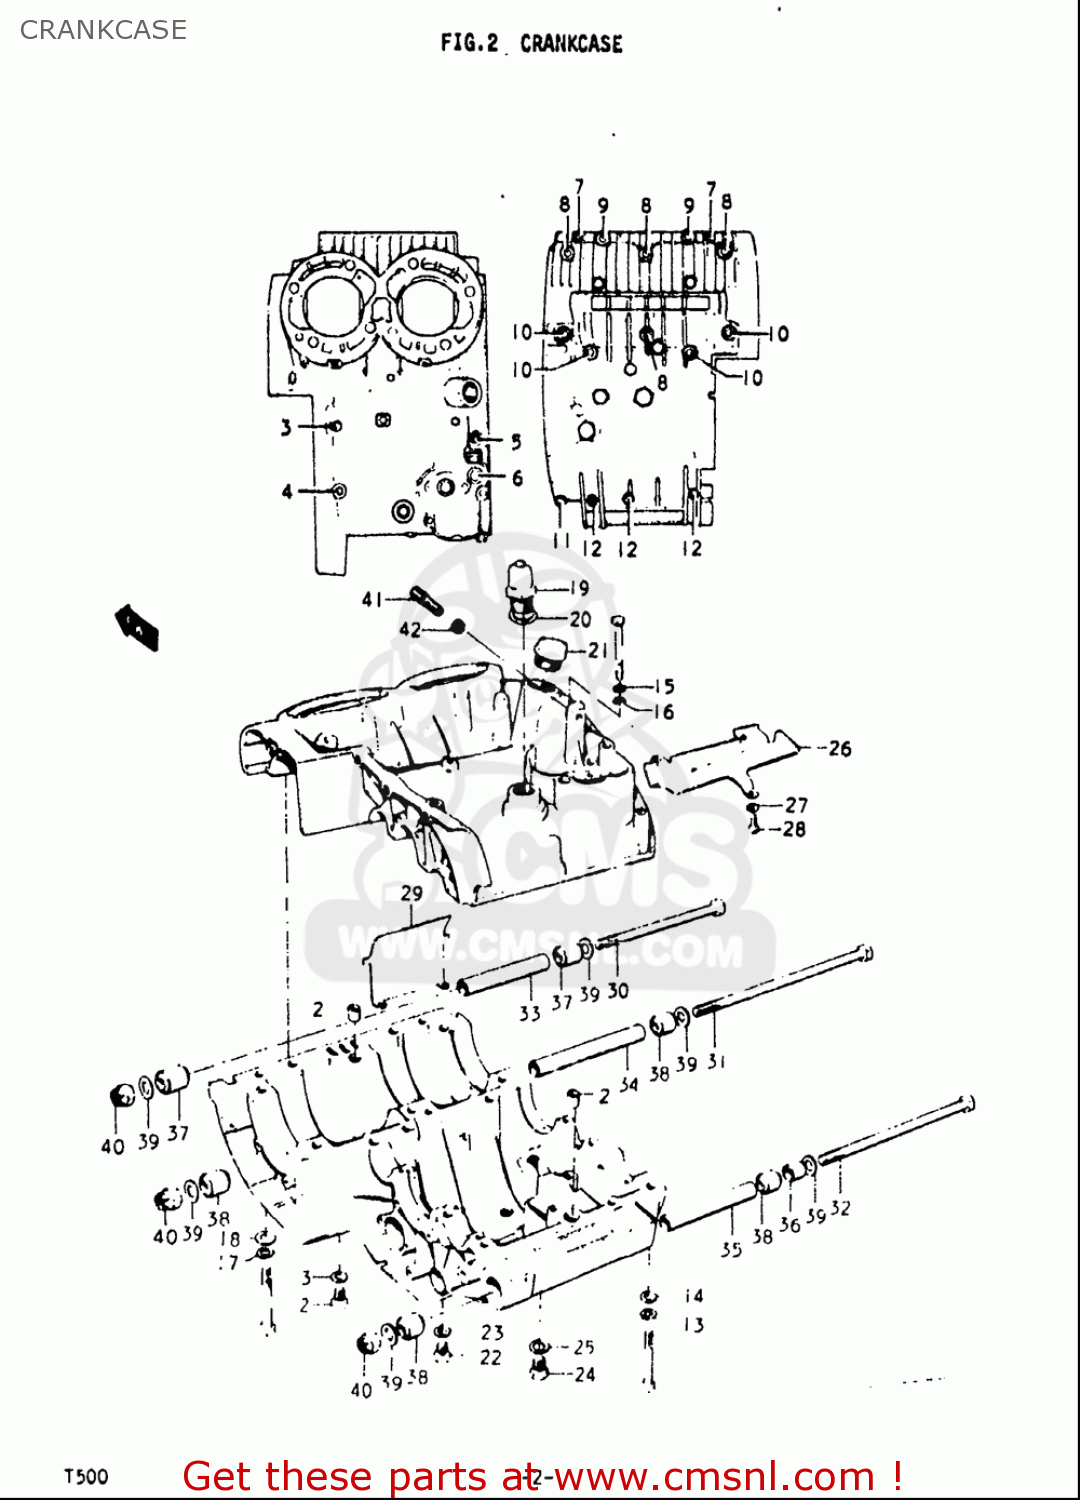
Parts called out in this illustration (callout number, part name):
2	PIN
3	BOLT(6X70)
4	BOLT
5	BOLT 6X95 HEXAG
6	BOLT
7	BOLT
8	BOLT
9	BOLT
11	BOLT
12	BOLT
13	WASHER,LOCK
14	WASHER
15	WASHER,LOCK
16	WASHER
17	WASHER,LOCK
18	WASHER
20	GASKET(18X24.2X2) (NAS)
21	PLUG SET
22	PLUG
23	GASKET(10X14X3.6) (NAS)
24	PLUG,12X9
25	GASKET(12X16X2) (NAS)
27	WASHER,LOCK
28	SCREW
37	BUSHING
39	WASHER
40	NUT
41	BOLT
42	NUT
